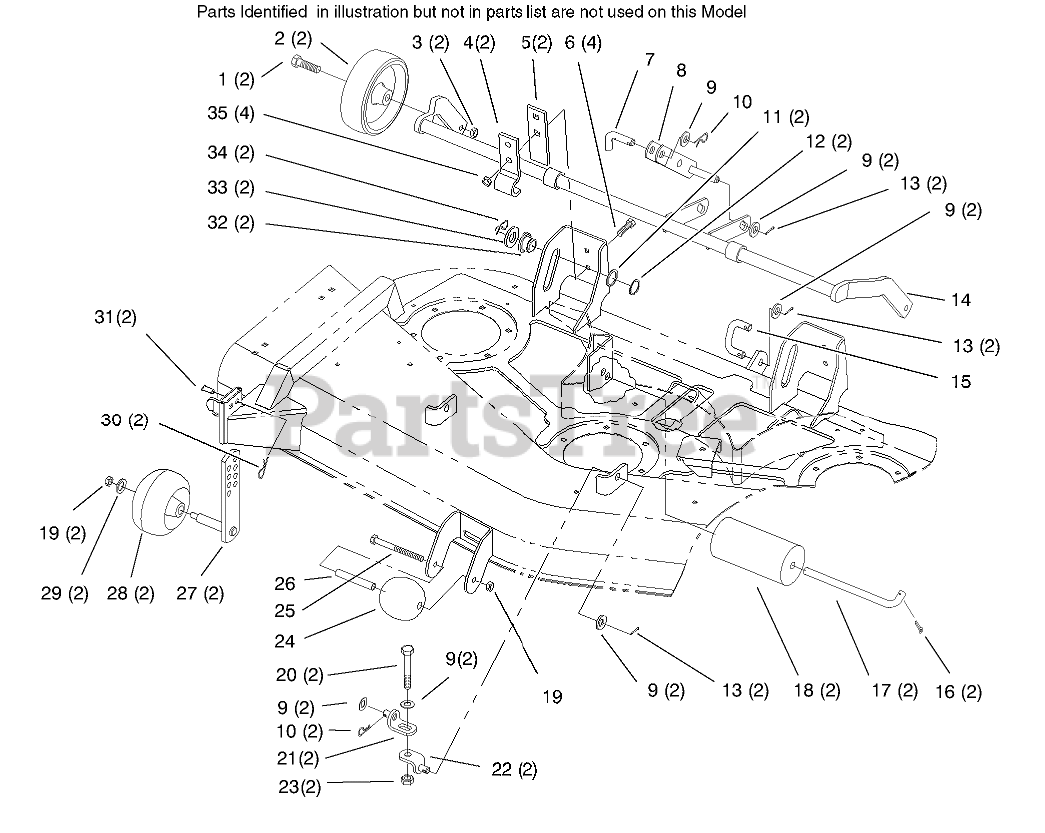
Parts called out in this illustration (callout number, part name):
1	BOLT-SHOULDER
2	WHEEL
3	NUT-HEX
4	Clamp
5	Bar
6	SCREW-HH
7	PIN-LINK
8	LIFT ARM ASSEMBLY
9	WASHER-FLAT
10	PIN-COTTER, HAIR
11	WASHER
12	RING-RETAINING
13	PIN-COTTER
14	WHEEL CARRIER ASSEMBLY
15	LINK - REAR
16	PIN-COTTER
17	SHAFT-ROLLER, REAR
18	ROLLER-DECK
19	NUT-LOCK, NI
20	SCREW-HH
21	BRACKET-LIFT, LOWER
22	BRACKET-LIFT, UPPER
23	NUT-JAM
24	ROLLER
25	SCREW-HH
26	TUBE-SPACER, WHEEL
27	GAGE-WHEEL
28	WHEEL-GAGE
29	WASHER-FLAT
30	PIN-HAIR
31	PIN-CLEVIS
32	ROLLER-LIFT
33	WASHER-FLAT
34	PIN-HAIR
35	NUT-HF
